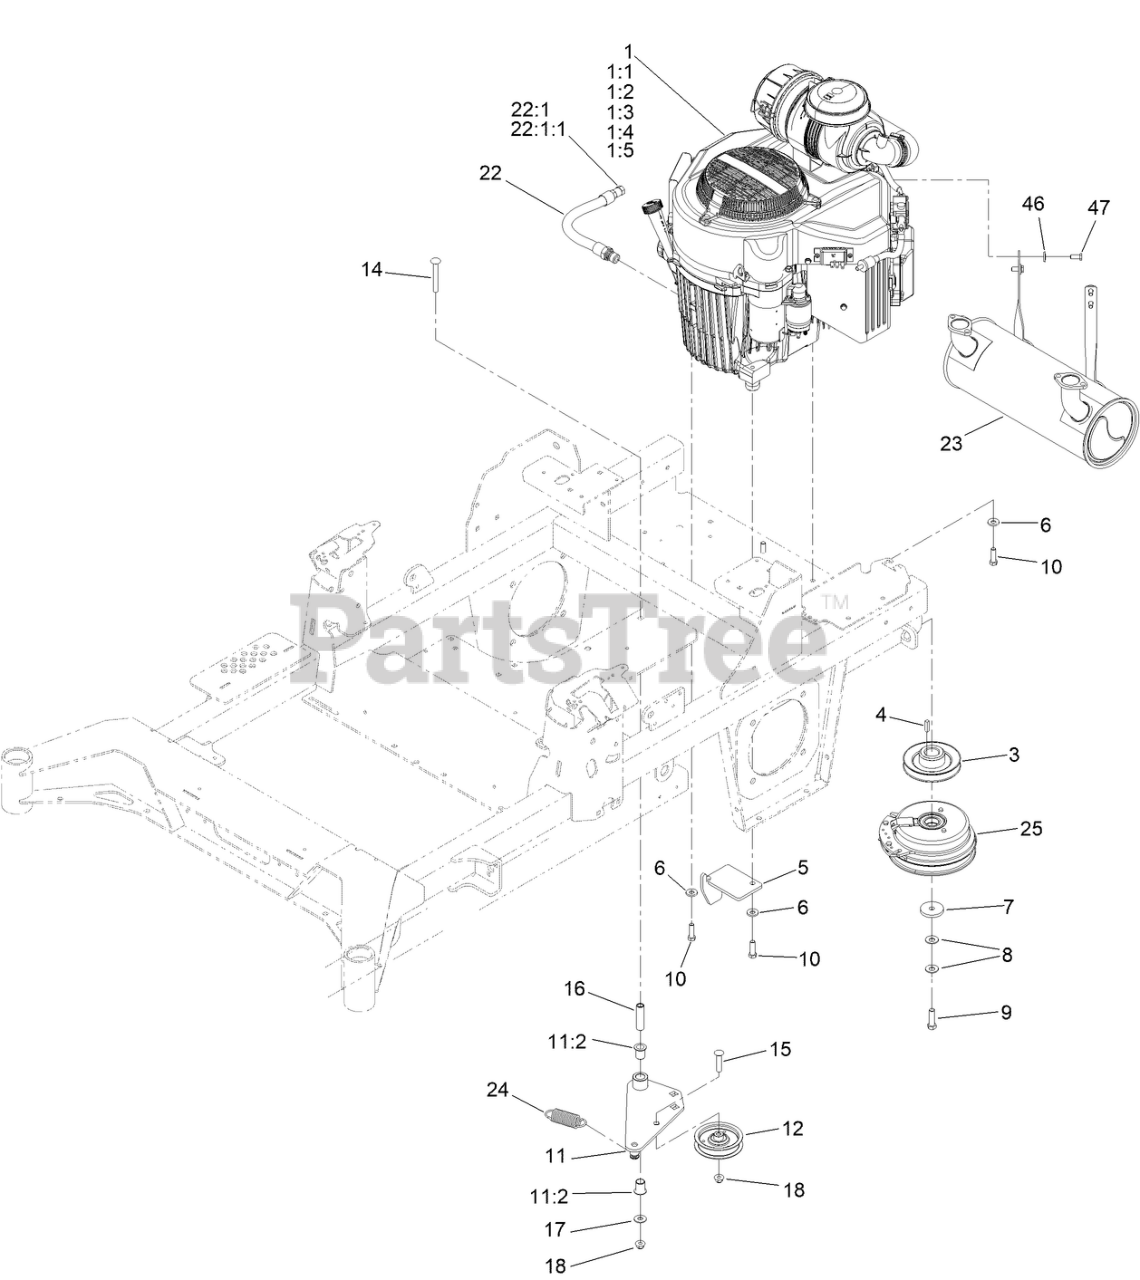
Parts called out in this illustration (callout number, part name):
1:1	FILTER-OIL
1:2	ELEMENT-FILTER, AIR (OUTER)
1:3	ELEMENT-FILTER, AIR (INNER)
1:4	FILTER-FUEL
1:5	SPARK PLUG
3	SHEAVE, W/HUB
5	ANCHOR-CLUTCH
6	WASHER-BELLEVILLE
7	WASHER-CLUTCH
8	WASHER-SPRING
9	SCREW-HH, W/LOCTITE
10	SCREW-HH
11	IDLER ARM ASM
11:2	BUSHING-FLANGE
12	PULLEY-IDLER, FLAT
14	SCREW-CARR
15	SCREW-CARR
16	BUSHING, IDLER PIVOT
17	WASHER-FLAT
18	NUT-HF, NI
22	ENGINE OIL DRAIN HOSE ASM
22:1	PLUG-HH
22:1:1	O-RING
23	MUFFLER
24	SPRING-IDLER
46	WASHER-SPRING
47	SCREW-HH
